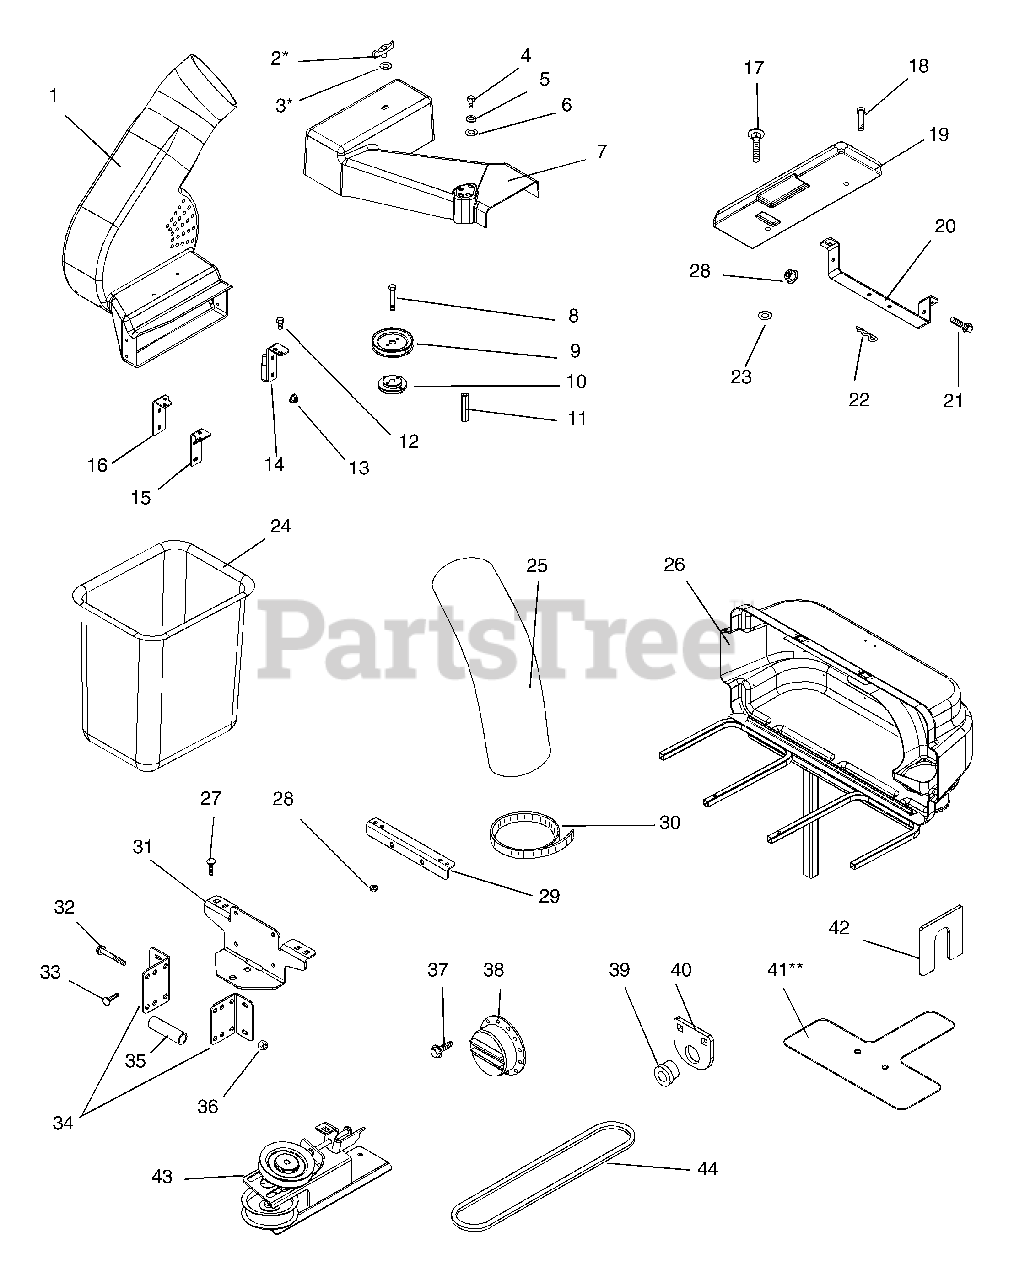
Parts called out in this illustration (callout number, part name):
1	Blower Assembly
2	KNOB - WING .312-18 UNC
3	WSHR-FL-STL .380X1.50X.062 YWZ
4	@BLT-HEX .38-16X.75 GR5 YWZC
5	@WSHR-LK .38X.094 REG YWZC
6	@WSHR-FL-STL.438X1.00X.083 YWZ
7	BELT COVER W/DECAL
8	BLT-HEX .38-16X1.75 GR8 M-EPYZ
9	SHEAVE, 3.00 DIA.
9	SHEAVE, 4.00 DIA.
10	ASSEMBLY, SHEAVE ADAPTER
11	NUT, COUPLING .38-16 X 2.97
12	@BLT-HEX .25-20X.75 GR5 YWZC
13	@NUT-LK-TOP-FLG .25-20 YWZC
14	WELDMENT, REAR MOUNT BRACKET
15	BRACKET, FRONT
16	WELDMENT, FRONT MOUNT BRACKET
17	@BLT-RDHDSQNK .38-16X1.00 G5YZ
18	PIN-CLEV .494X2.50 BRIGHT ZINC
19	WEIGHT, CAST IRON
20	BRACKET,WEIGHT
21	@BLT-HEX .38-16X1.00 GR5 YWZC
22	PIN-HAIR-EXT .12X.31X2.37 YWZC
23	WSHR-FL-STL .515X1.625X.250 YZ
24	GRASS BAGGER BASKET
25	HOSE 7 X 45
26	Cover Assembly
27	@BLT-RDHDSQNK .38-16X2.50 G5YZ
28	@NUT-LK-TOP-FLG .38-16 YWZC
29	BRKT,ANGLE
30	CLAMP, 7" TOOL-LESS HOSE
31	TRAILER HITCH W/DECALS
32	@BLT-HEX .50-13X3.00 GR5 YWZC
33	@BLT-RDHDSQNK .38-16X1.25 G5YZ
34	BKT,BAGGER MOUNT
35	SPACER, PIVOT .500X.750X1.805
36	@NUT-LK-TOP-FLG .50-13 YWZC
37	SCR-TAP 8-32X.38 SL HWH YWZC
38	DEFLECTOR,EXHAUST
39	BSHG-FLG 1.000X1.12X.62X1.50BR
40	BRACKET,REAR PIVOT
41	GUARD,FINGER
42	PLATE,LIFT
43	Idler Assembly
44	V-BELT, HA-WRAPPED
44	V-BELT, HA-RAW EDGE
